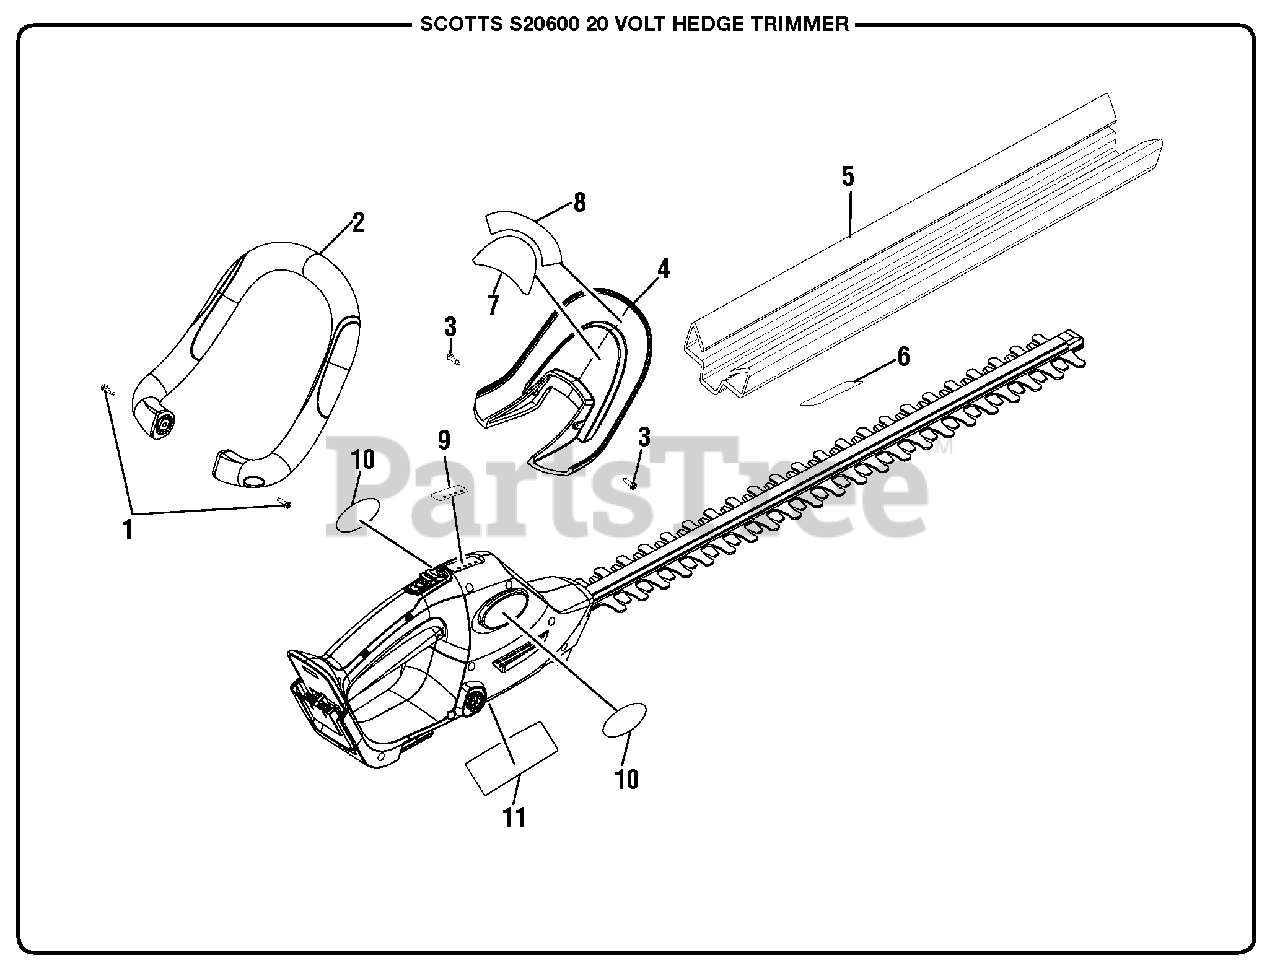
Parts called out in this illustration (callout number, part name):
1	Screw (M4 x 28 mm)
3	Screw (M3 x 12 mm)
4	Guard Assembly
6	Blade Strap Label
7	Warning Label
8	Icon Label
9	Fuel Gauge Label
10	Logo Label
11	Data Label
